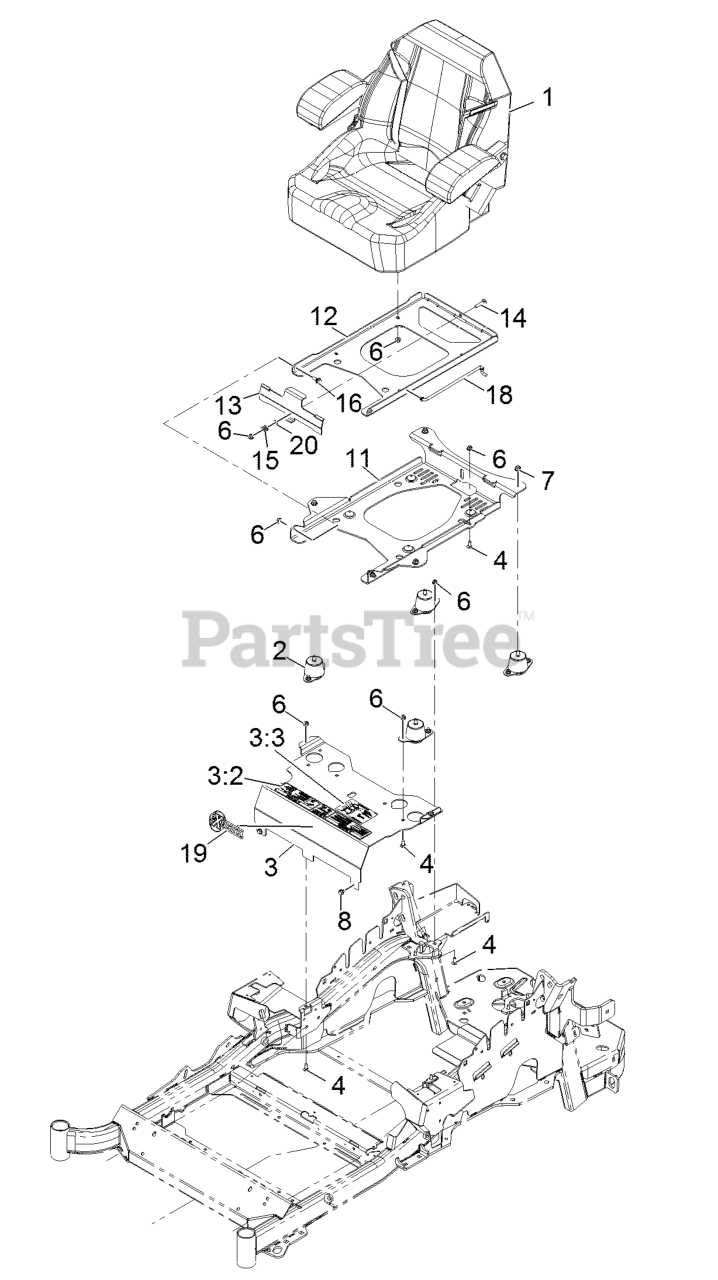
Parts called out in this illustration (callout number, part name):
2	ISOLATOR-SEAT
3	MOUNT-SEAT
3:2	DECAL-CONSOLE
3:3	DECAL-SERVICE AID
4	SCREW-CARR
6	NUT-HF, NI
7	NUT-HF, NI
11	PLATE-TILT, SEAT SUPPORT
12	PLATE-FRAME, SEAT
13	PLATE-LATCH, SEAT
14	BOLT-CARR
15	SPRING-COMPRESSION
16	SCREW-SHOULDER
18	ROD-PROP
20	WASHER-PLAIN
